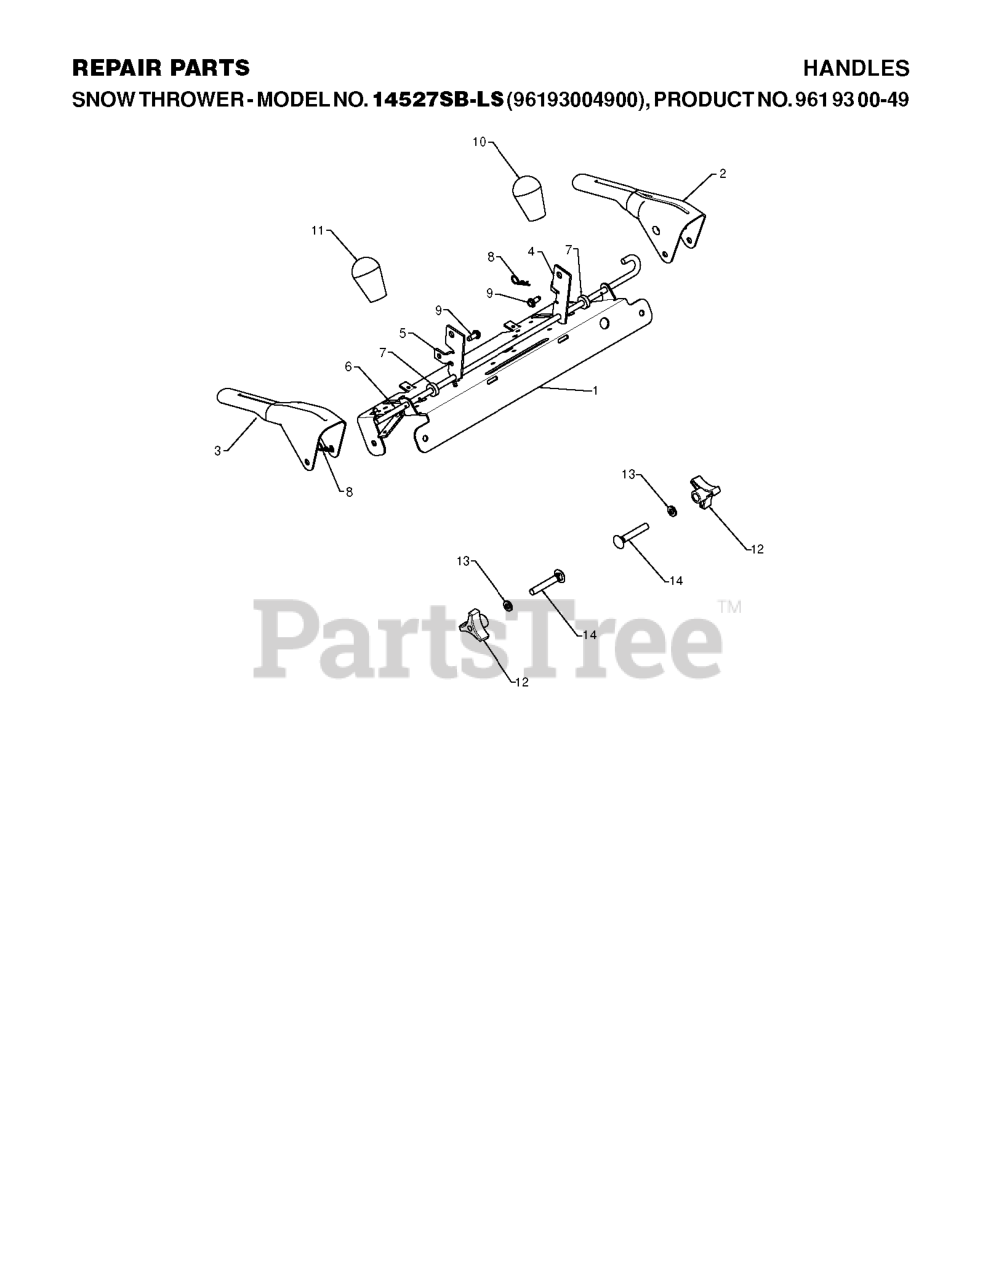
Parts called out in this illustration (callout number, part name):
1	PANEL.CONTROL
2	LEVER.CONTROL.LH.BLACK
3	LEVER.CONTROL.RH.GREY
4	ARM.TRACTION.ROD.YZ
5	ARM.IMPELLER.ROD.SNOW
6	BAIL.CONTROL.INTERLOCK
7	SPACER.CONTROL.LEVER
8	SPRING RETAINER
9	SCREW 14-20 X 5/8
10	KNOB LEVER, BLACK
11	RED KNOB SHIFTER
12	KNOB.HANDLE.3/8.TRI-POINT.BLAC
13	WASHER
14	BOLT 3/8-16 X 2-1/4
